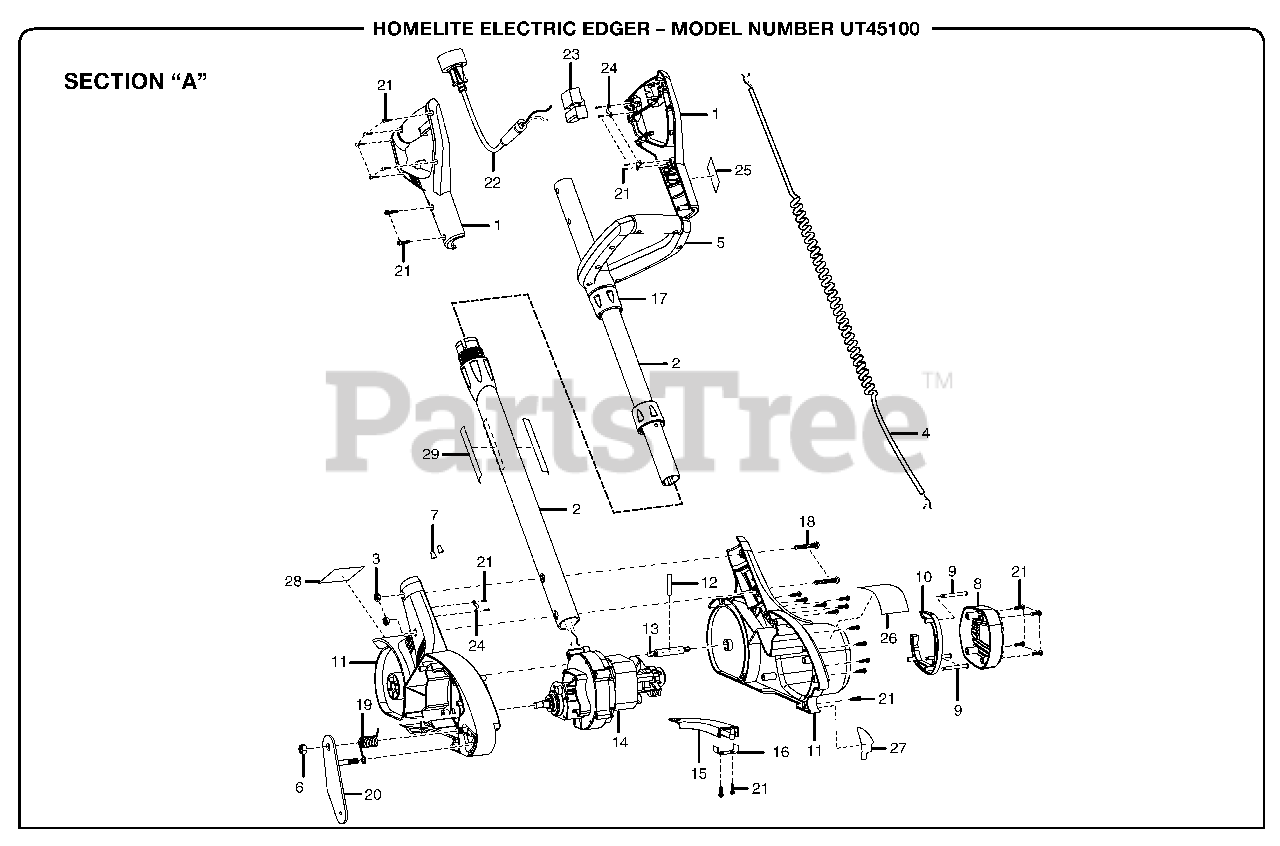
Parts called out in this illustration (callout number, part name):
1	Handle Assembly
2	Pole Assembly
3	Hex Nut
4	Spring Cord Assembly
5	Auxiliary Handle Assembly
6	Lock Nut
8	Motor Cover
9	Screw
10	Air Damper
11	Housing Assembly
14	Motor Assembly
15	Air Outlet
16	Air Outlet Cover
18	Screw
19	Torsion Spring
20	Front Wheel Arm
21	Screw
22	Power Cord
24	Cord Clamp
25	Handle Label
26	Data Label
27	Depth Adjustment Label
28	Curb Runner Label
29	Logo Label
